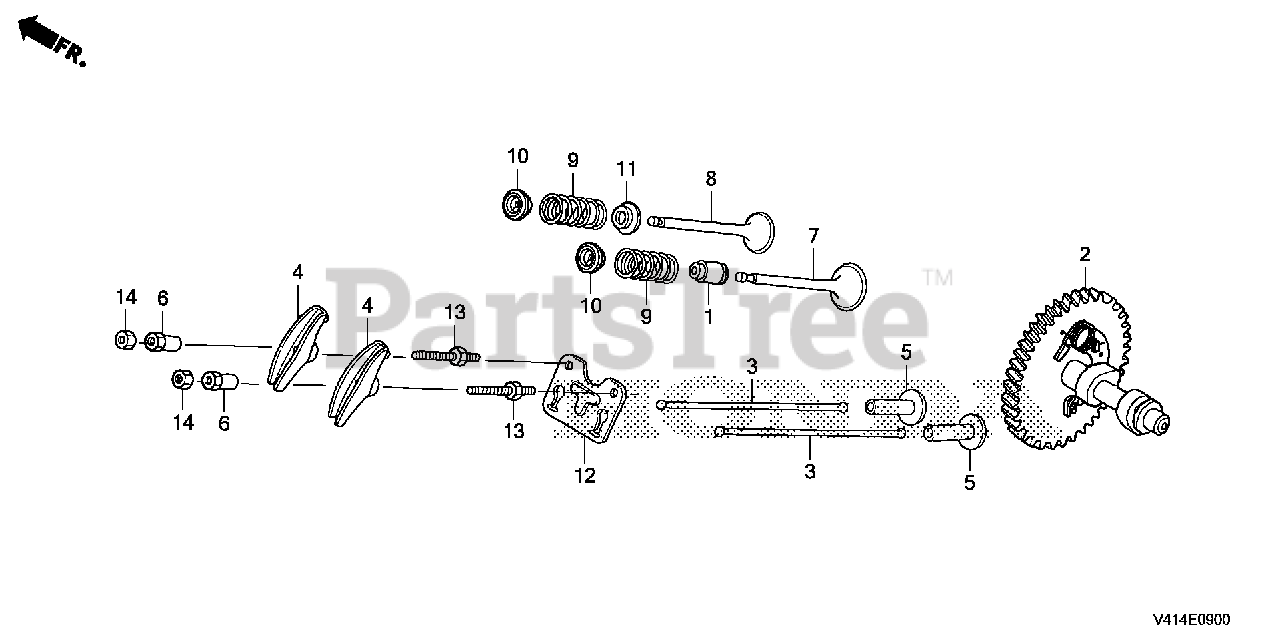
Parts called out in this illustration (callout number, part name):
1	SEAL, VALVE STEM
2	CAMSHAFT (STD)
4	ARM, VALVE ROCKER
5	LIFTER, VALVE
6	PIVOT, ROCKER ARM
7	VALVE, IN.
8	VALVE, EX.
9	SPRING, VALVE
10	RETAINER, IN. VALVE SPRING
11	SEAT, VALVE SPRING
12	GUIDE, PUSH ROD
13	BOLT, PIVOT (8MM)
14	NUT, PIVOT ADJUSTING
